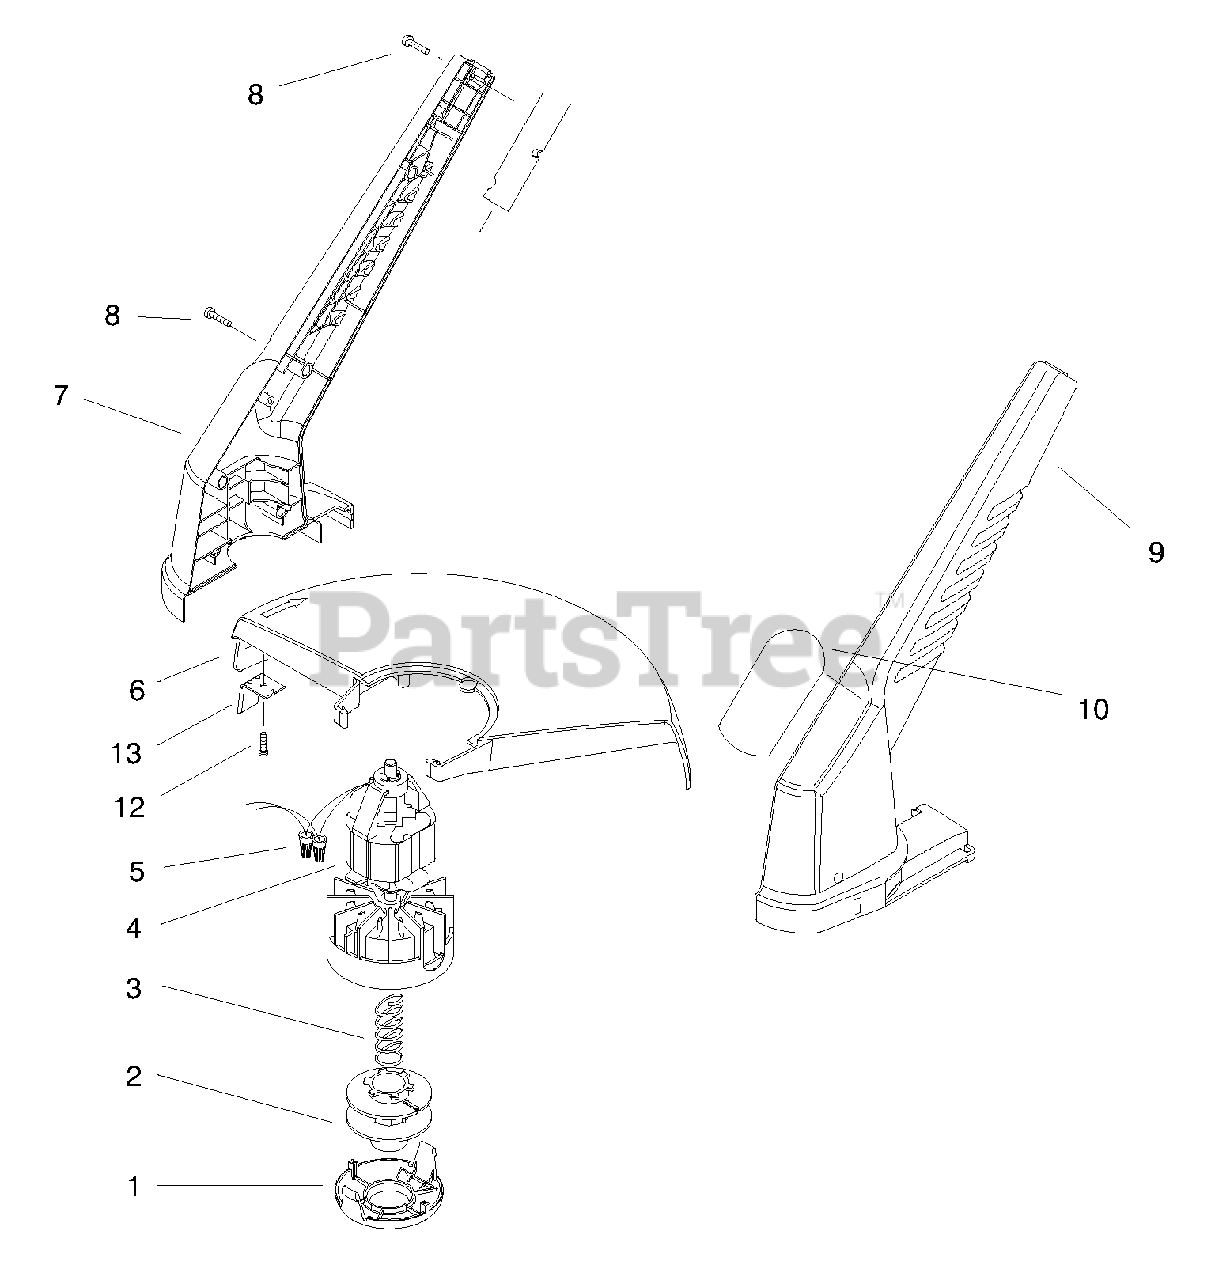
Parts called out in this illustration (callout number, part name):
4	Motor Assembly
5	Connector-Wire Nut
6	Shield Asm.-15" (Incl. Ref. #12 and 13)
7	Housing R.H.
8	Screw-Pan Hd.
9	Housing L.H.
10	Decal-15" Trimmer
